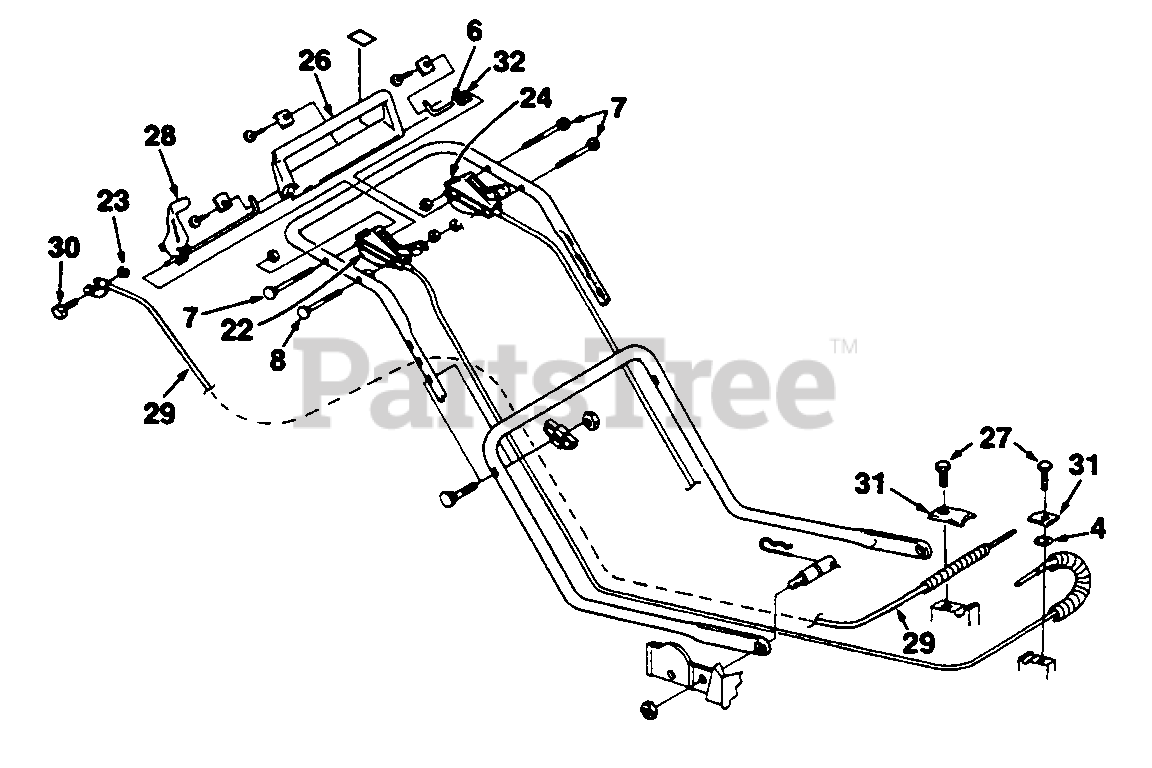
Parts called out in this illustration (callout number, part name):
4	WASHER, LOCK
6	SHAFT - Pivot
7	BOLT- Sq. neck
8	BOLT- Sq. neck
22	CONTROL- Manual start
23	NUT-Lock (1/4-20)
24	CONTROL- Throttle
26	BAIL- Brake control
27	SCREW- 1/4-20 x 5/8"
28	TRACTION LEVER ASSY.
29	CONTROL CABLE TBO
30	SCREW - 1/4-20 x 1 1/2"
32	SPRING - Compression
